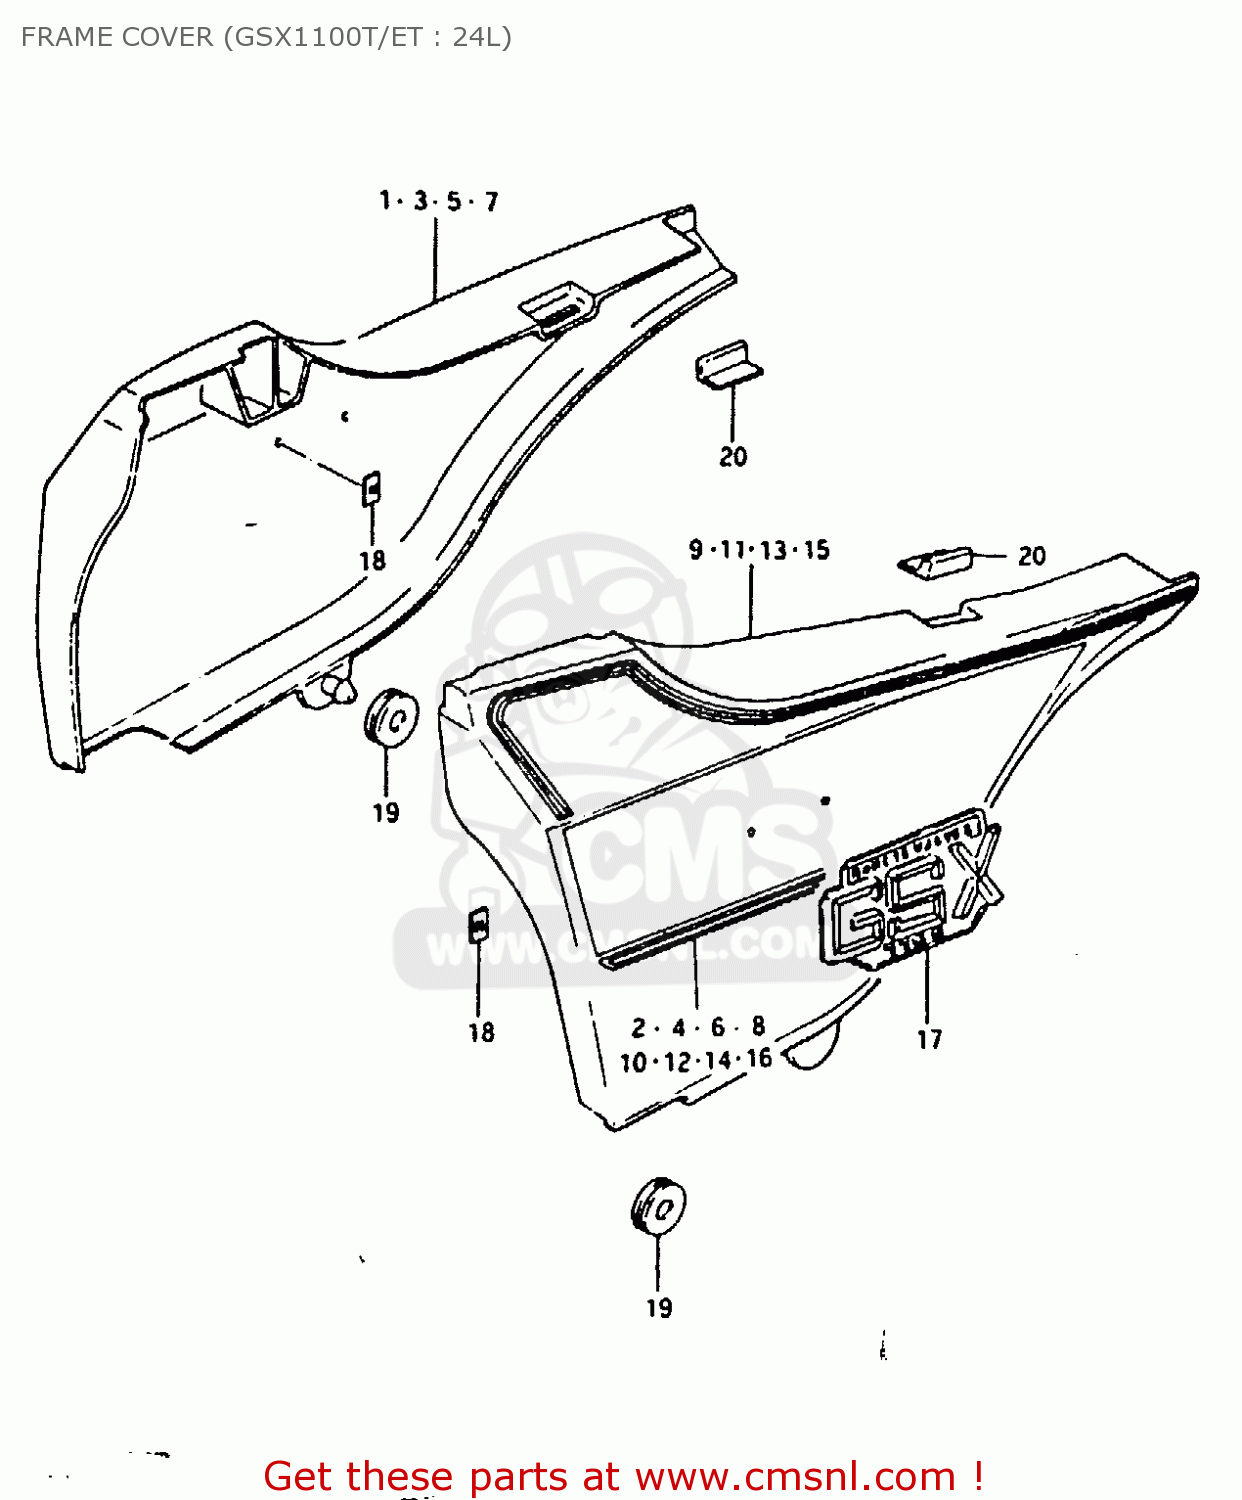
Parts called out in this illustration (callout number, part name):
1	COVER, FRAME RH (BLACK)
2	TAPE SET, RH
3	COVER,FRAME,RIGHT
4	TAPE SET, RH
5	COVER, FRAME RH (RED)
6	TAPE SET, RH
7	COVER, FRAME RH (BLUE)
8	TAPE SET, RH
9	COVER, FRAME LH (BLACK)
10	TAPE SET, LH
11	COVER,FRAME,LEFT
12	TAPE SET, LH
13	COVER, FRAME LH (RED)
14	TAPE SET, LH
15	COVER, FRAME LH (BLUE)
16	TAPE SET, LH
17	EMBLEM,FRAME COVER
18	NUT
19	CUSHION
20	CUSHION,FRAME COVER
